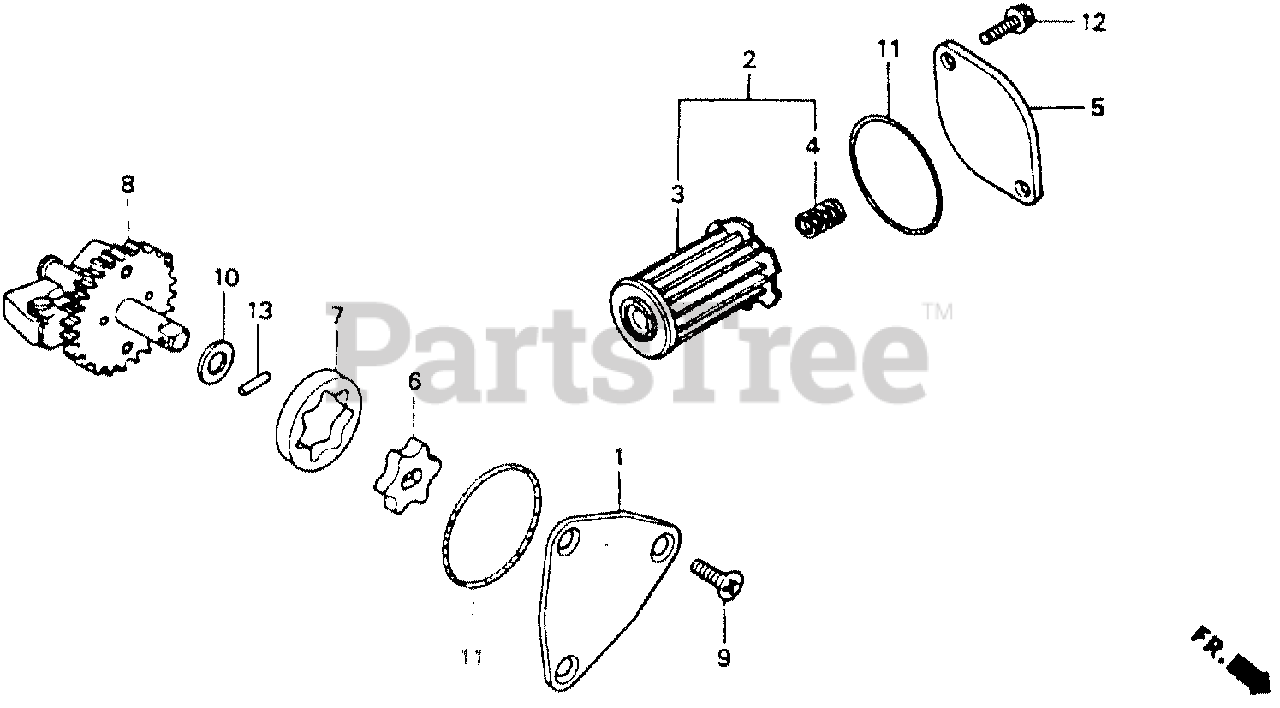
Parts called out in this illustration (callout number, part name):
1	COVER, OIL PUMP
2	STRAINER, OIL
3	STRAINER, OIL
4	SPRING, OIL STRAINER
5	COVER, OIL STRAINER
6	ROTOR, OIL PUMP (INNER)
7	ROTOR, OIL PUMP (OUTER)
8	WEIGHT, GOVERNOR
9	SCREW, FLAT (6X16)
10	WASHER (10.1MM)
11	O-RING (42.2X2.4)
12	BOLT, FLANGE (6X16)
13	ROLLER (3X13.4)
